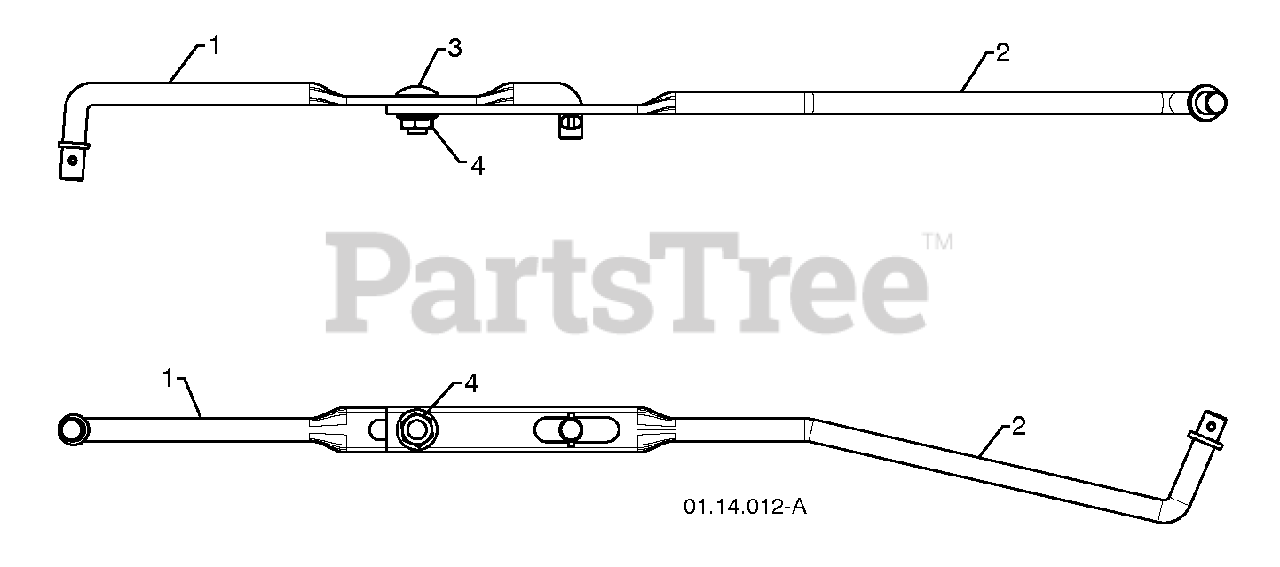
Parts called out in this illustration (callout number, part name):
1	SHIFTER ROD TOP
2	SHIFTER ROD BOTTOM
3	CARRIAGE BOLT 5/16-18 X .75
4	NUT 5/16-18
